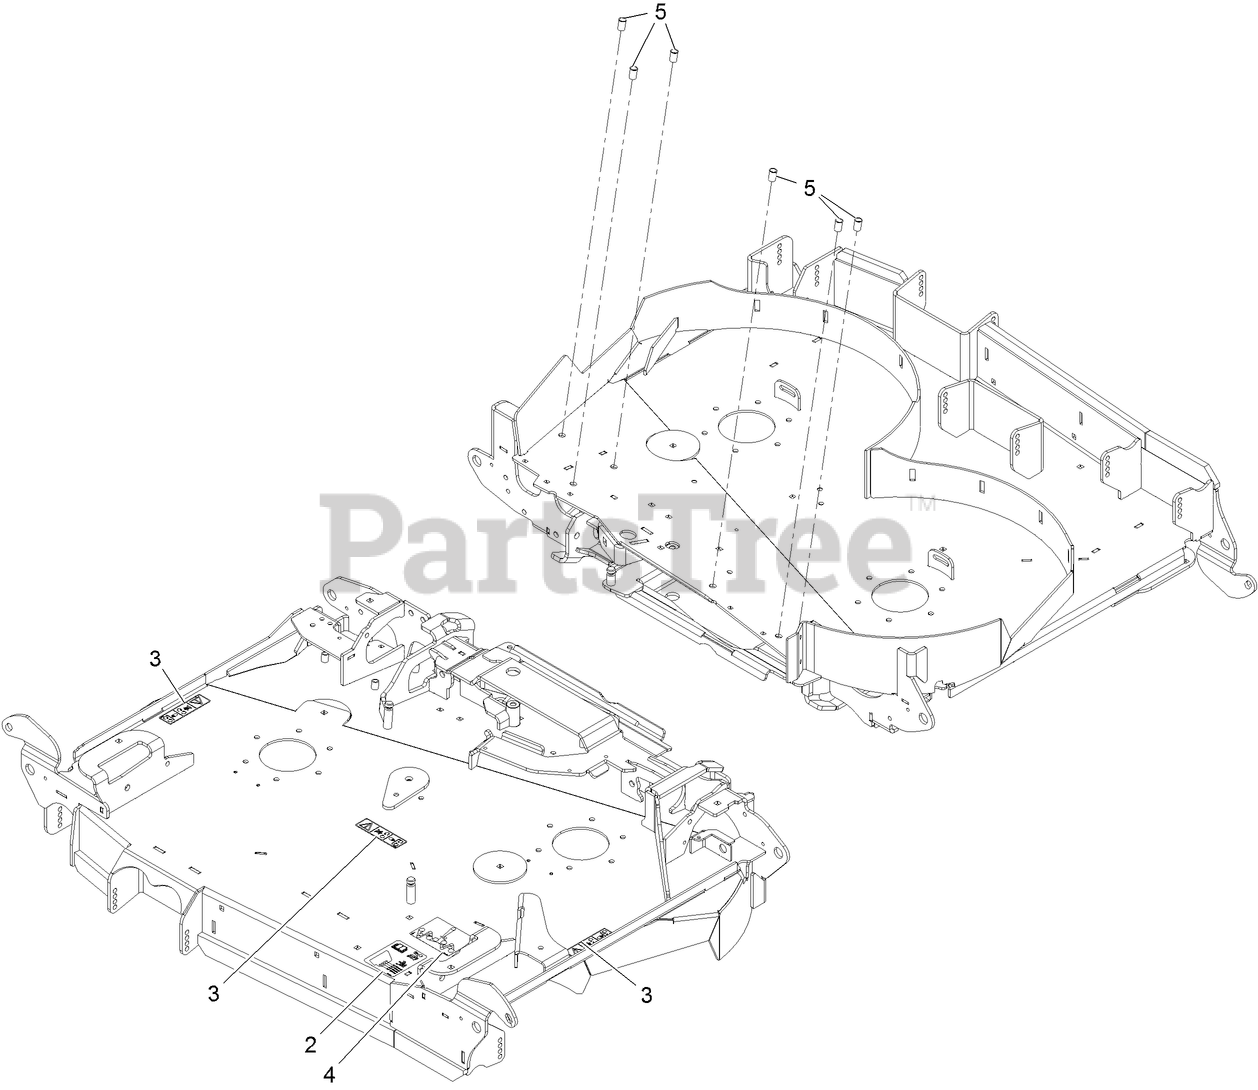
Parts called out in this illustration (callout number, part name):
2	DECAL-ROLLER, ANTI-SCALP
3	DECAL-COVER, MISSING
4	Decal-Belt Routing
5	NUT-CLINCH
